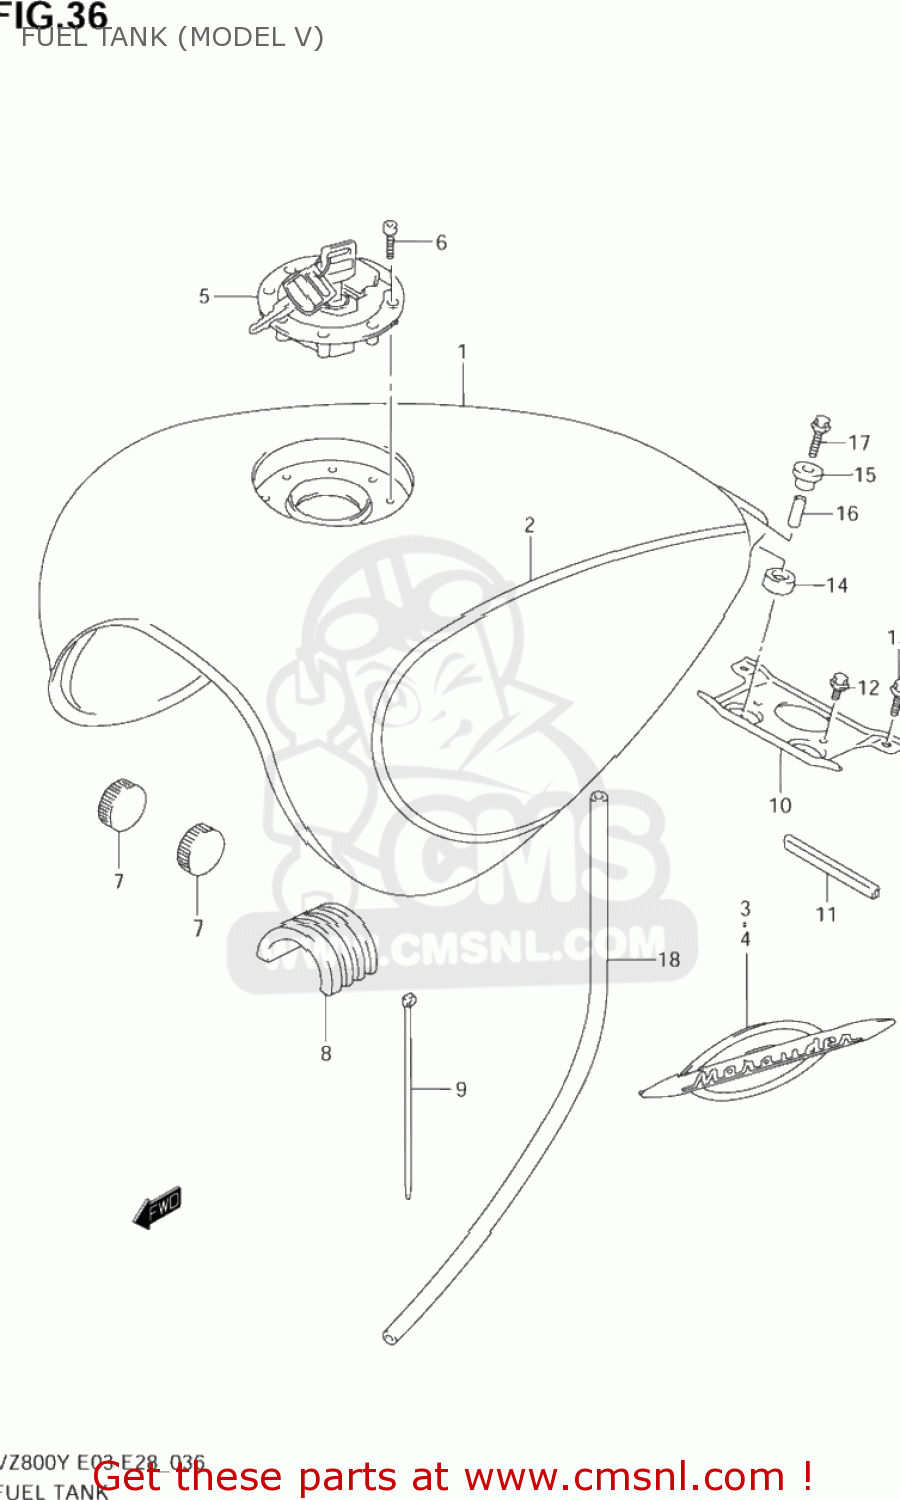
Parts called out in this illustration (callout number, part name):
1	TANK ASSY,FUEL
2	TAPE SET,FUEL TANK
3	EMBLEM,FUEL TANK,R
4	EMBLEM,FUEL TANK,L
5	CAP SET,FUEL TANK
6	BOLT(5X20)
7	CUSHION
8	CUSHION,FUEL TANK UPR
9	CLAMP(L:250)
10	BRACKET,FUEL TANK,REAR
11	PROTECTOR
12	BOLT
13	BOLT
14	CUSHION,FUEL TANK RR NO.2
15	CUSHION
16	SPACER(6.5X10.5X22.5)
17	BOLT
18	HOSE,DRAIN
